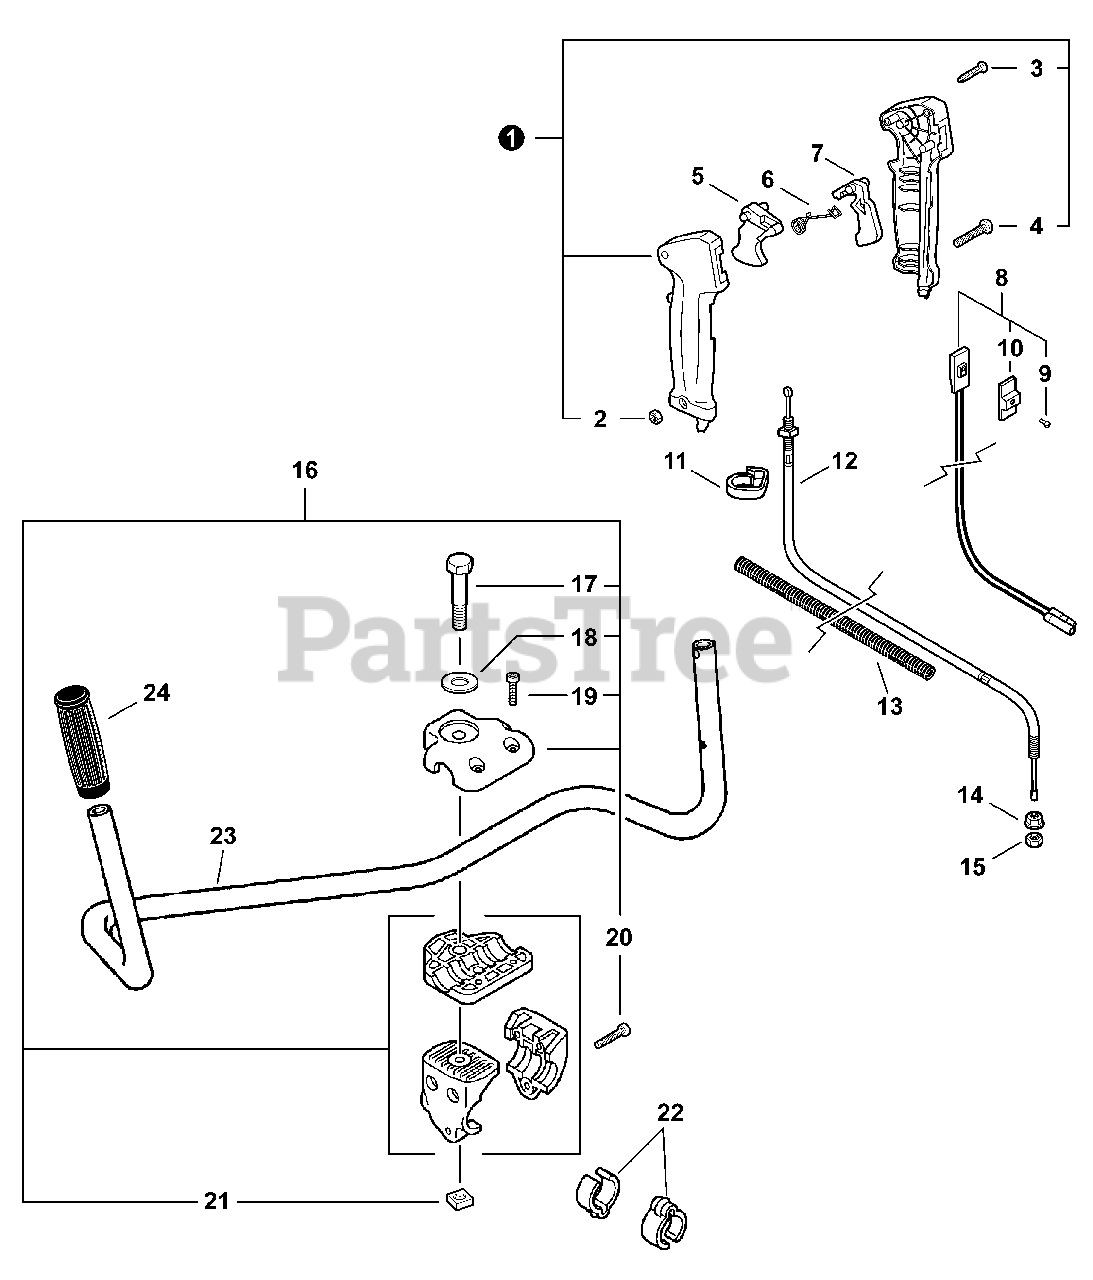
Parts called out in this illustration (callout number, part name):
1	THROTTLE CONTROL ASSY
3	SCREW - 3×25
4	SCREW - 5×30
5	TRIGGER, THROTTLE
6	SPRING, THROTTLE LOCK
7	LOCKOUT, TRIGGER
8	SWITCH, IGNITION
9	SCREW - 3×10
10	KNOB, SWITCH - ORANGE
12	CABLE, THROTTLE
13	TUBE, PROTECTIVE - CORRUGATED
14	NUT - 6 -- FLANGE
16	HANDLE BRACKET KIT
17	BOLT - 8×55
18	WASHER - 8
19	SCREW - 5×20
20	SCREW - 5×25
23	HANDLE - FRONT
24	GRIP, HANDLE - LEFT
